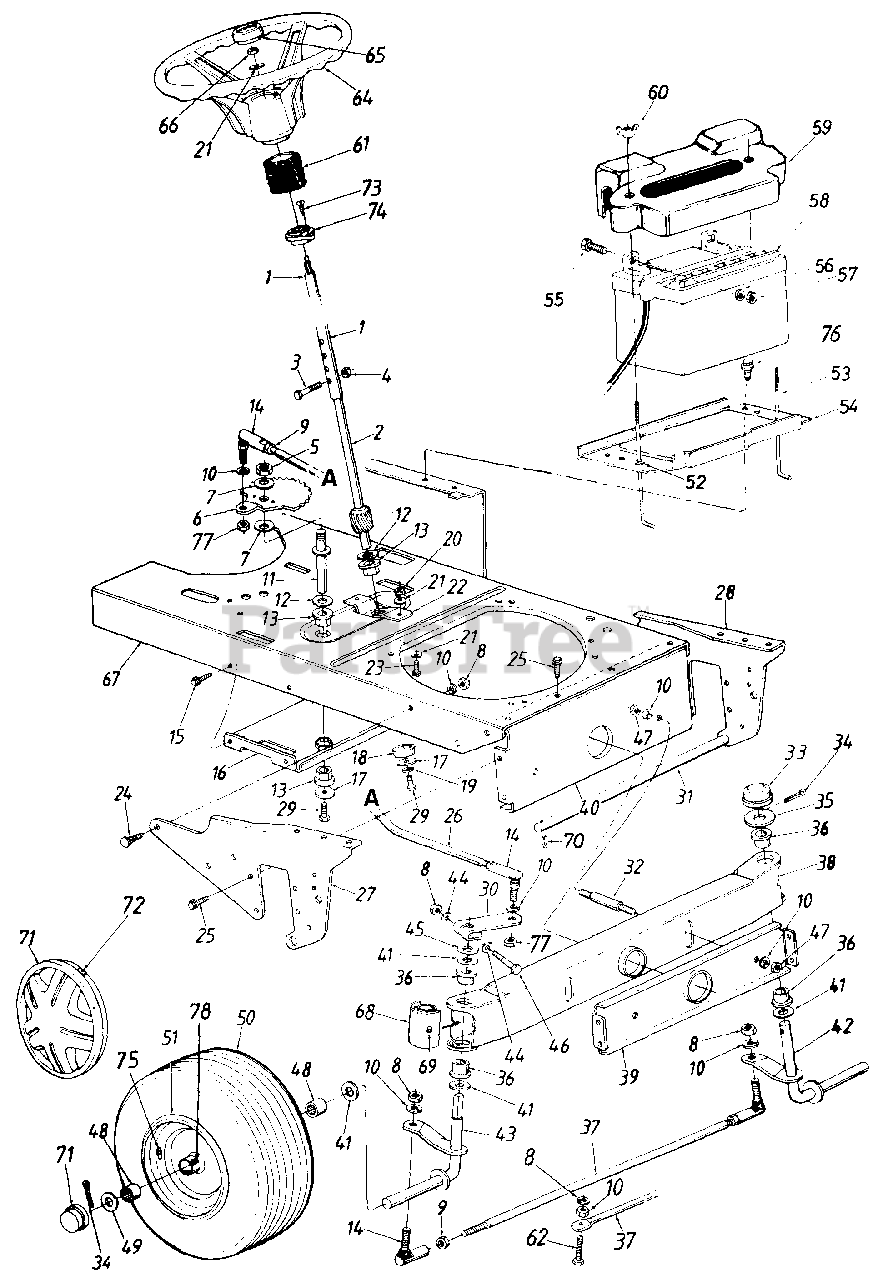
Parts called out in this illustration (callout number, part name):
1	Steering Column Ass'y.
2	Lower Steering Shaft
3	Hex Bolt 1/4-20 x 1.31" Lg.
4	Hex L-Nut 1/4-20 Thd.
5	Hex Jam Nut 5/8-18 Thd.
6	Steering Gear Segment
7	Bell-Wash. 5/8" I.D. x 1.25" O.D.
8	Hex Nut 3/8-24 Thd.
9	Hex Jam Nut 3/8-24 Thd.
10	L-Wash. 3/8" I.D.
11	Steering Gear Segment Shaft
12	Fl-Wash. .64" I.D. x 1.24" O.D.
13	Hex Flange Brg. .63" I.D.
14	Ball Joint Ass'y.
15	Hex Wash. Hd. TT-Tap Scr. 1/4-20 x .5" Lg.
16	Deck Idler Support Brkt.
17	Fl-Wash. .33" I.D. x 1.25" O.D.
18	Spacer .985" I.D. x 1.25" O.D.
19	L-Wash. 5/16" I.D.
20	Hex Nut 5/16-24 Thd.
21	Bell-Wash. .345" I.D. x .88" O.D.
24	Ribbed Neck Bolt 3/8-24 x .8" Lg.
25	Hex Wash. TT-Tap Scr. 5/16-18 x .62" Lg.
26	Steering Drag Link
27	Pivot Bar Side Plate - R.H.
28	Pivot Bar Side Plate - L.H.
29	Hex Bolt 5/16-18 x .62" Lg.
30	Steering Arm
31	Deck Connecting Rod
32	Pivot Bar Shld. Bolt 3/8-16 x 5/8" Lg.
33	Cap
34	Cotter Pin 5/32" Dia.
35	Flat Washer
36	Flange Brg. .757" I.D.
37	Tie Rod 20.25" Lg. (Adjustable)
38	Pivot Bar Assy.
41	Fl-Wash. .76" I.D. x 1.49" O.D.
42	Front Axle Ass'y.- L.H.
43	Front Axle Ass'y.- R.H.
44	Bowed Washer
45	Spacer .755" I.D. x 1.25" O.D.
46	Hex Bolt 3/8-24 x 2.25" Lg.
47	Hex Nut 3/8-16 Thd.
48	Flange Brg. .75" I.D.
49	Fl-Wash. .71" I.D. x 1.5" O.D.
50	Wheel Ass'y. Comp.
51	Rim Only
52	Push Nut
53	Battery Hold Down Rod
54	Battery Plate
56	L-Wash. 1/4" I.D.
57	Hex Nut 1/4-20 Thd.
58	Battery (275 Cold Crank Amps)
59	Battery Cover
60	Wing Nut Plastic 1/4-20 Thd.
61	Steering Bellow
62	Hex Bolt 3/8-24 x 1.5" Lg. (Gr. 5)
64	Steering Wheel (3 Spoke)
65	Steering Wheel Cap
66	Hex L-Nut 5/16-24 Thd.
67	Lower Frame
68	Pivot Bar End Cap
69	Grease Fittings
70	Internal Cotter Pin
71	Hub Cap
72	Spring Clip
73	Oval Hd. Cr.-Sunk Scr. #10 x 5/8" Lg.
74	Flange Brg. .89" I.D. x 1.36" O.D.
75	Air Valve
76	Hex AB-Tap Scr. 1/4 x .62" Lg.
77	Hex Jam L-Nut 3/8-24 Thd.
78	Grease Fitting
